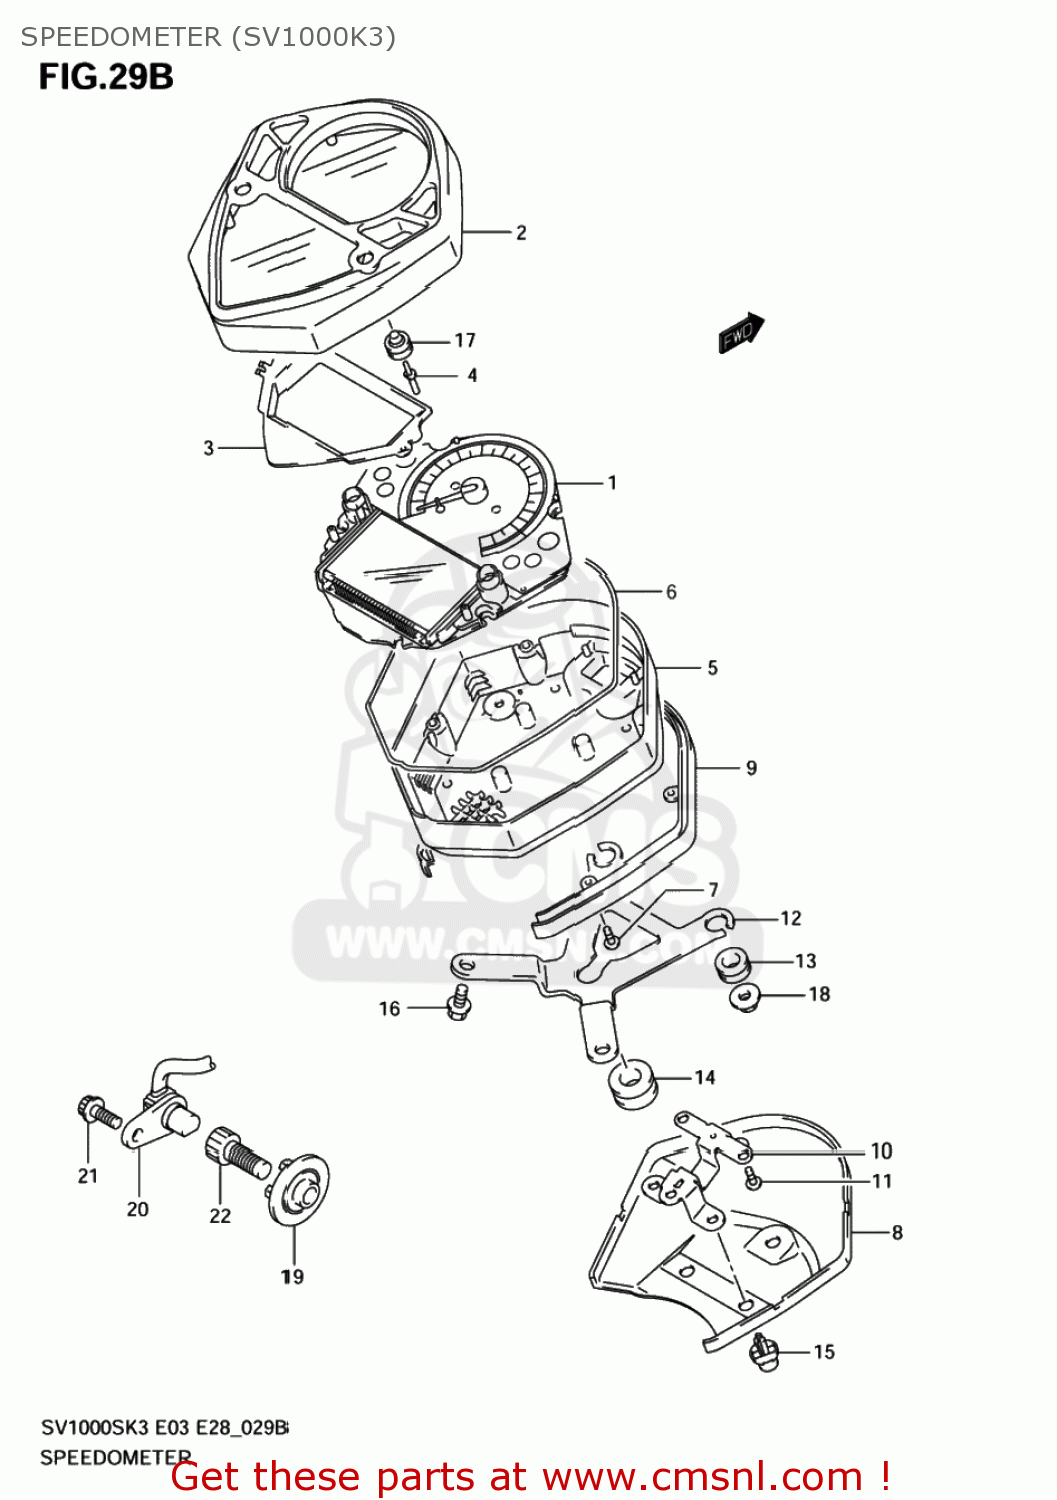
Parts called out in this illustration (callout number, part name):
1	SPEEDOMETER
2	CASE,SPEEDOMETER UPR
3	PLATE,SPEEDOMETER
4	KNOB,SPEEDOMETER
5	CASE,SPEEDOMETER LWR
6	GASKET,METER CASE (NAS)
7	SCREW,SPEEDOMETER
8	COVER,SPEEDOMETER LWR
9	DECORATION PLATE,METER CASE
10	HOLDER,SPEEDOMETER
11	SCREW(4X14)
12	BRACKET,SPEEDOMETER
13	CUSHION,METER
14	CUSHION
15	CLIP
16	BOLT MAGNETO S
17	COVER,SPEEDOMETER KNOB
18	NUT
19	ROTOR,SPEED
20	SENSOR,SPEED
21	BOLT
22	BOLT
